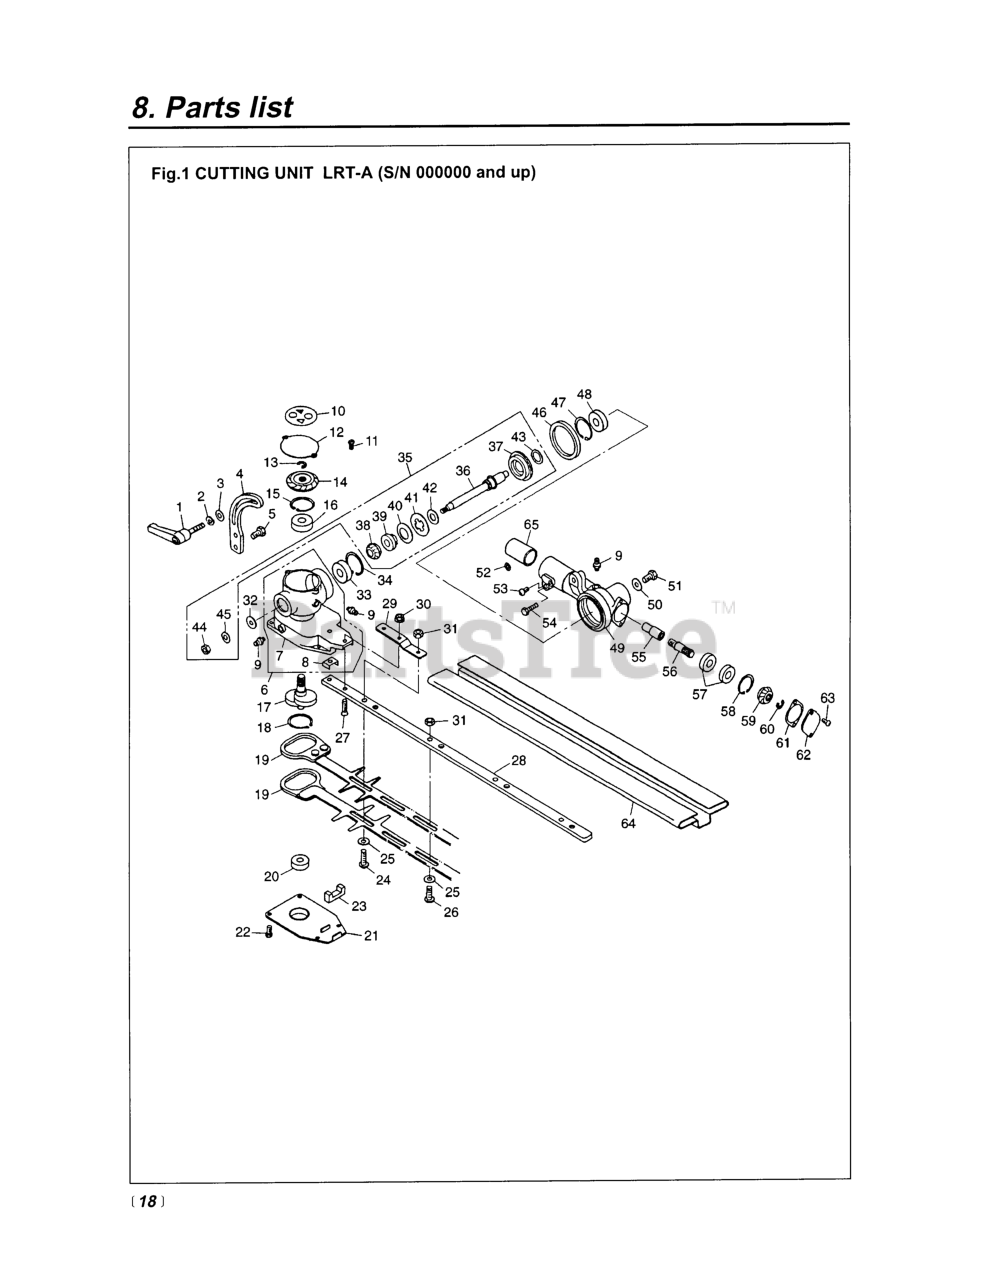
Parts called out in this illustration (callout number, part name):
2	WASHER, M6 X 15
3	WASHER, 6 X 6 X 2.0
4	ADJUSTER, ANGLE (USE-13141)
6	CASING (RPLS -13210)
7	CASING A
8	PLATE
9	FITTING, GREASE
11	SCREW, M4 X 8
13	RING, SNAP
14	GEAR, BEVEL
15	RING, SNAP, M26 X 1.2
16	BEARING
17	CRANKSHAFT
18	RING, SNAP, M28 X 1.5
19	BLADE (RPLS -13410) 18
20	BEARING
23	FELT
25	WASHER (RPLS 3873-11760)
26	SCREW
27	SCREW, M5 X 20
28	PLATE, GUIDE
29	PLATE (RPLS 6780- )
30	NUT, M5
31	NUT, M6
32	WASHER, 6X15X2.0
33	BEARING
34	RING, SNAP, M22 x 1.2
35	KIT, SHAFT (RPLS 6782-13610)
36	SHAFT
37	GEAR (B)
38	GEAR (C)
39	BOSS
40	WASHER, SPRING
41	PLATE
42	WASHER
43	WASHER
44	NUT, M6 X 5
45	WASHER, M6 X 15
46	O-RING
47	RING, SNAP, M26 X 1.2
48	BEARING
49	CASING
50	WASHER, 6 X 6 X 2.0
52	WASHER
53	BOLT, M5 X 10
54	BOLT
55	JOINT (REPLACES T3078-13810)
56	SHAFT, GEAR
57	BEARING
58	RING, SNAP, M22 x 1.2
59	GEAR, BEVEL
60	RING, SNAP
61	PACKING
62	COVER, STOPPER KIT
63	SCREW, M4 X 8
64	COVER, BLADE
